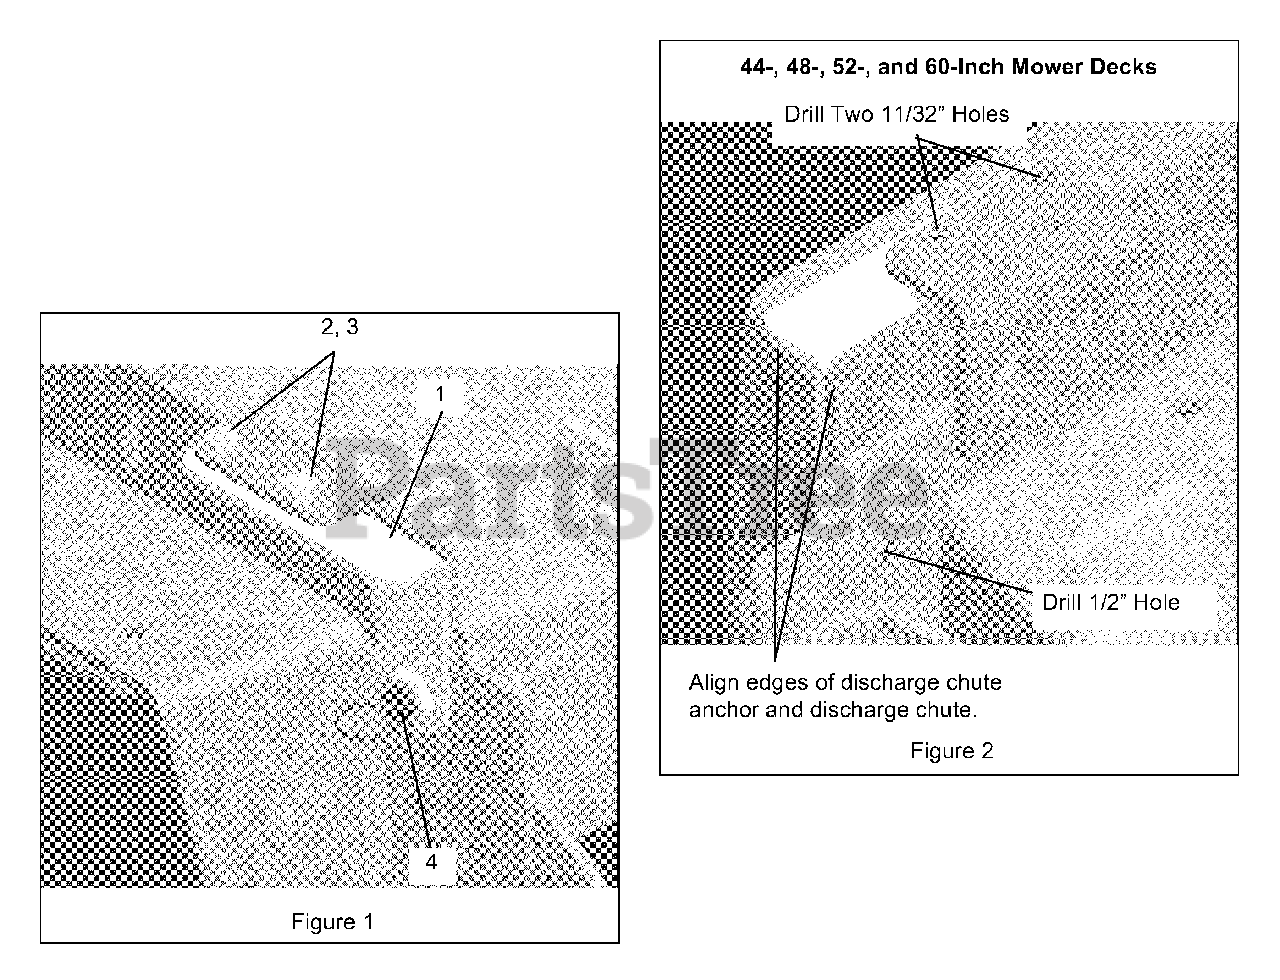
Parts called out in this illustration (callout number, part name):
1	Discharge Chute Anchor
2	5/16" Hex Bolt
3	5/16" Top Lock Flange Nut
4	1/2" Pull Pin
